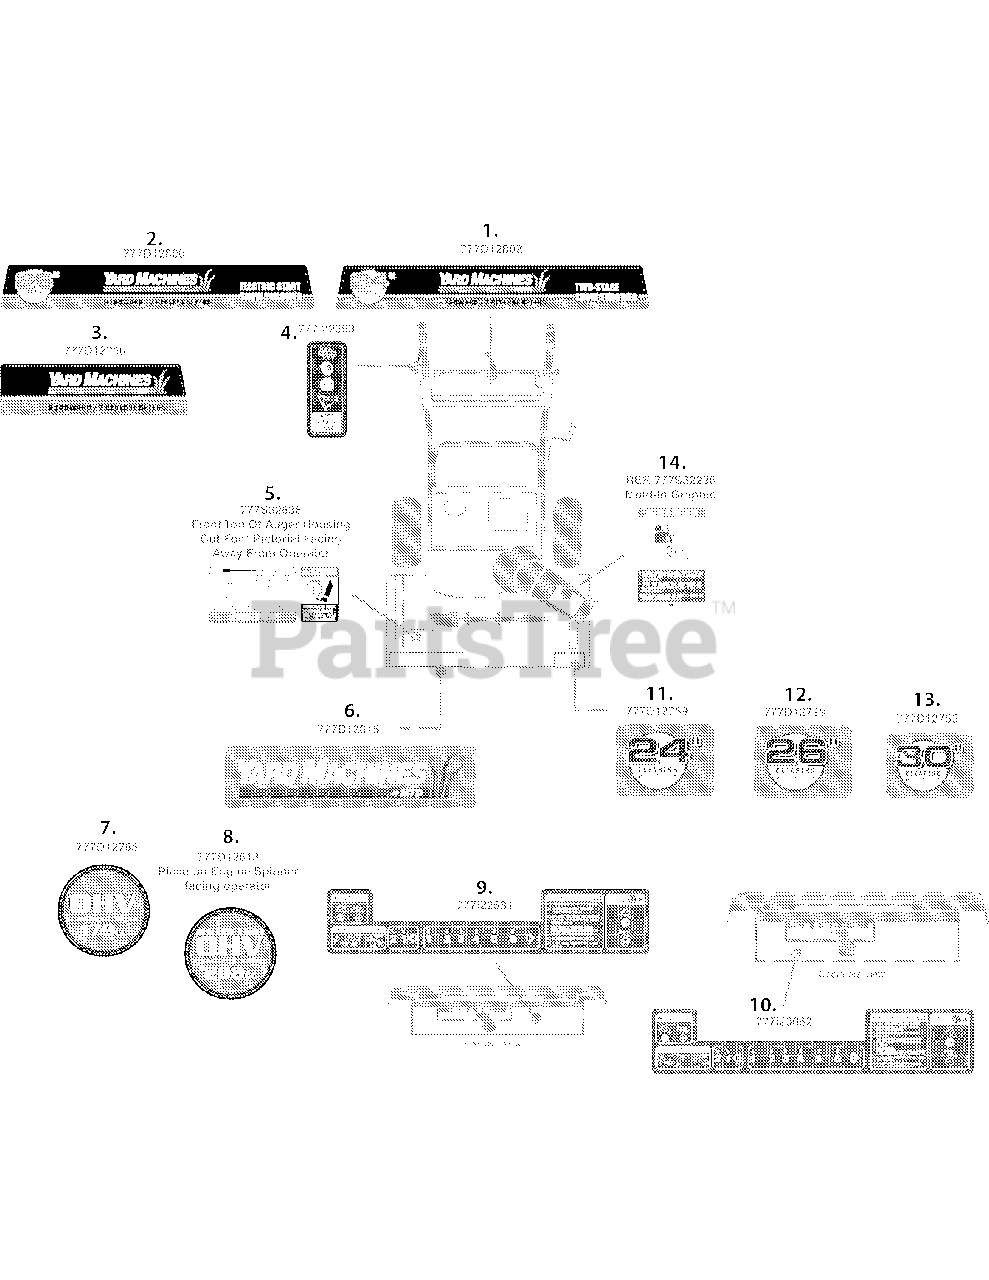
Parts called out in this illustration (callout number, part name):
1	LABEL:SNOW:HNDPAN:YM:24/6/2/2STG
2	LABEL:SNOW:HNDLPANL:YMACH:26/6/2
3	LABEL:SNOW:FRT/HNDL/PAN:YM:6/2
4	LABEL:DRV/AUGR LOCK
5	LABEL:SNOW HOUSING
6	LABEL:SNOW:FRNT/LFTAUG:YMACH
7	LABEL:ENG/SPN:OHV/179
8	LABEL:ENG/SPN:OHV/ES/208
9	LABEL:OPERATOR PAN
10	LABEL:SNOW:E/F PNL:ST INSTR:B&S
11	LABEL:SNOW:FRNT/RTAUG:YMACH:24
12	LABEL:SNOW:FRNT/RTAUG:YMACH:26
13	LABEL:SNOW:FRNT/RTAUG:YMACH:30
14	LABEL:SNOW CHUTE
